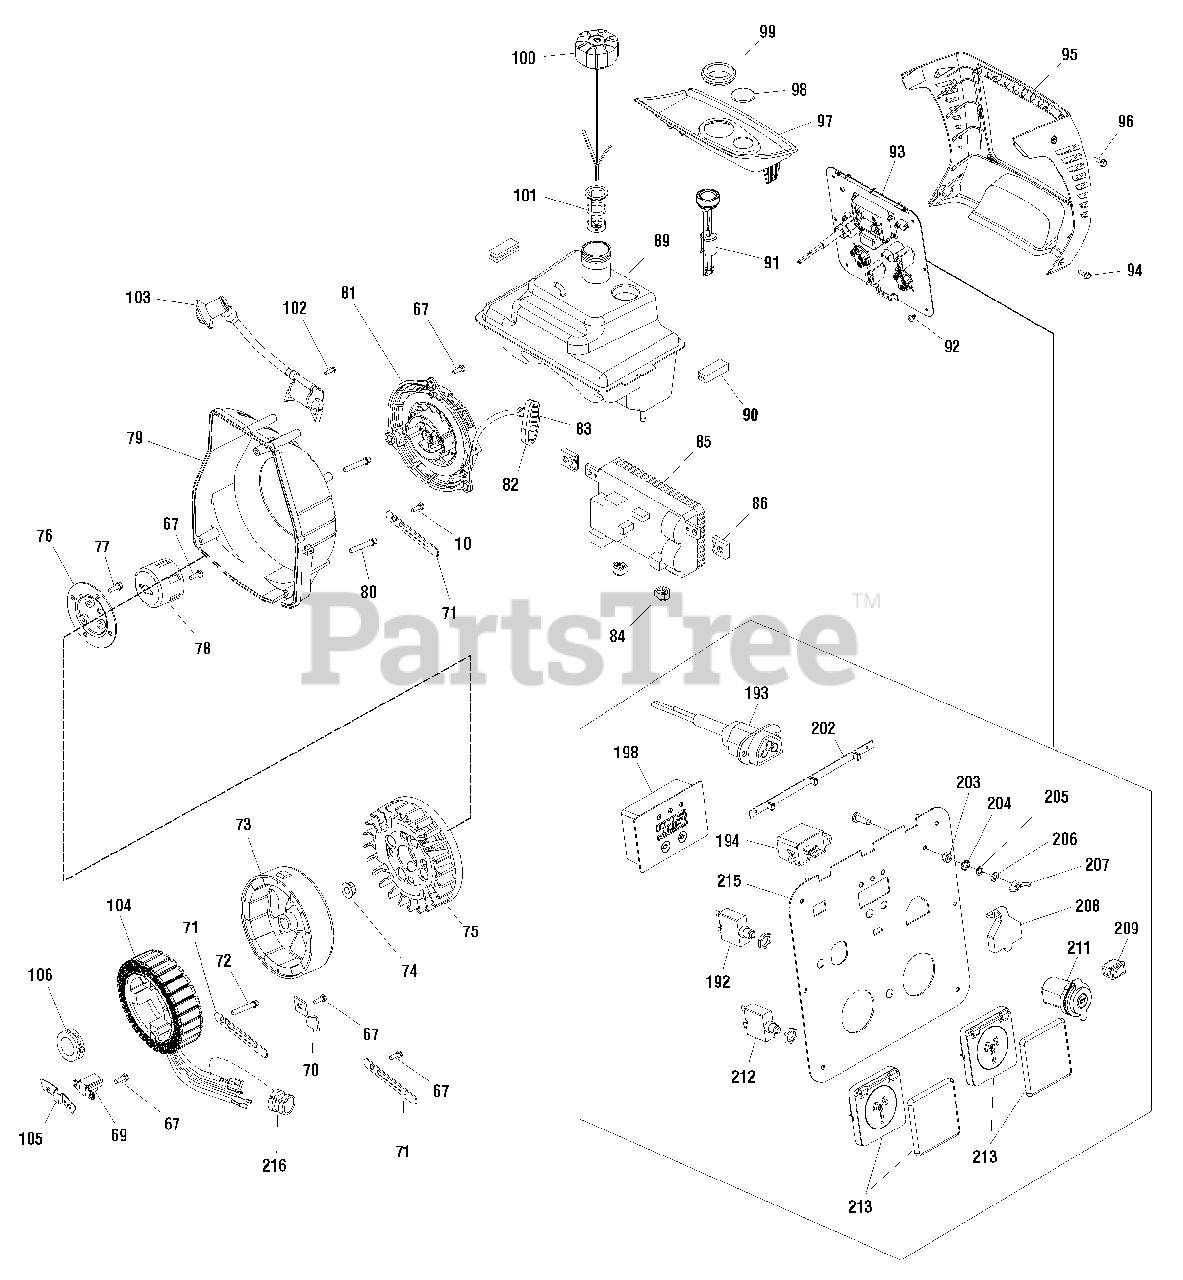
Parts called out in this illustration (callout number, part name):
10	SCREW
67	BOLT-M6 x 12
69	TRIGGER-IGNITION
70	BRACKET
71	BRACKET
72	SCREW-M6 x 60
74	NUT, FLANGE M14
76	TERMINAL
77	BOLT-M6 x 16
79	COVER-FAN
80	BOLT-M6 x 55
81	STARTER-REWIND
83	INSERT-GRIP
84	MOUNT-VIBRATION
86	MOUNT-VIBRATION
90	MOUNT-VIBRATION
92	SCREW
94	SCREW-M5 x 30
96	SCREW-M6 x 56
101	FILTER-FILLER NECK
102	SCREW
103	COIL-IGNITION
105	BRACKET
106	SEAL-OIL
192	BREAKER-CIRCUIT
193	PORT-PARALLEL
212	BREAKER-CIRCUIT
215	PANEL-CONTROL
216	COVER-RUBBER
